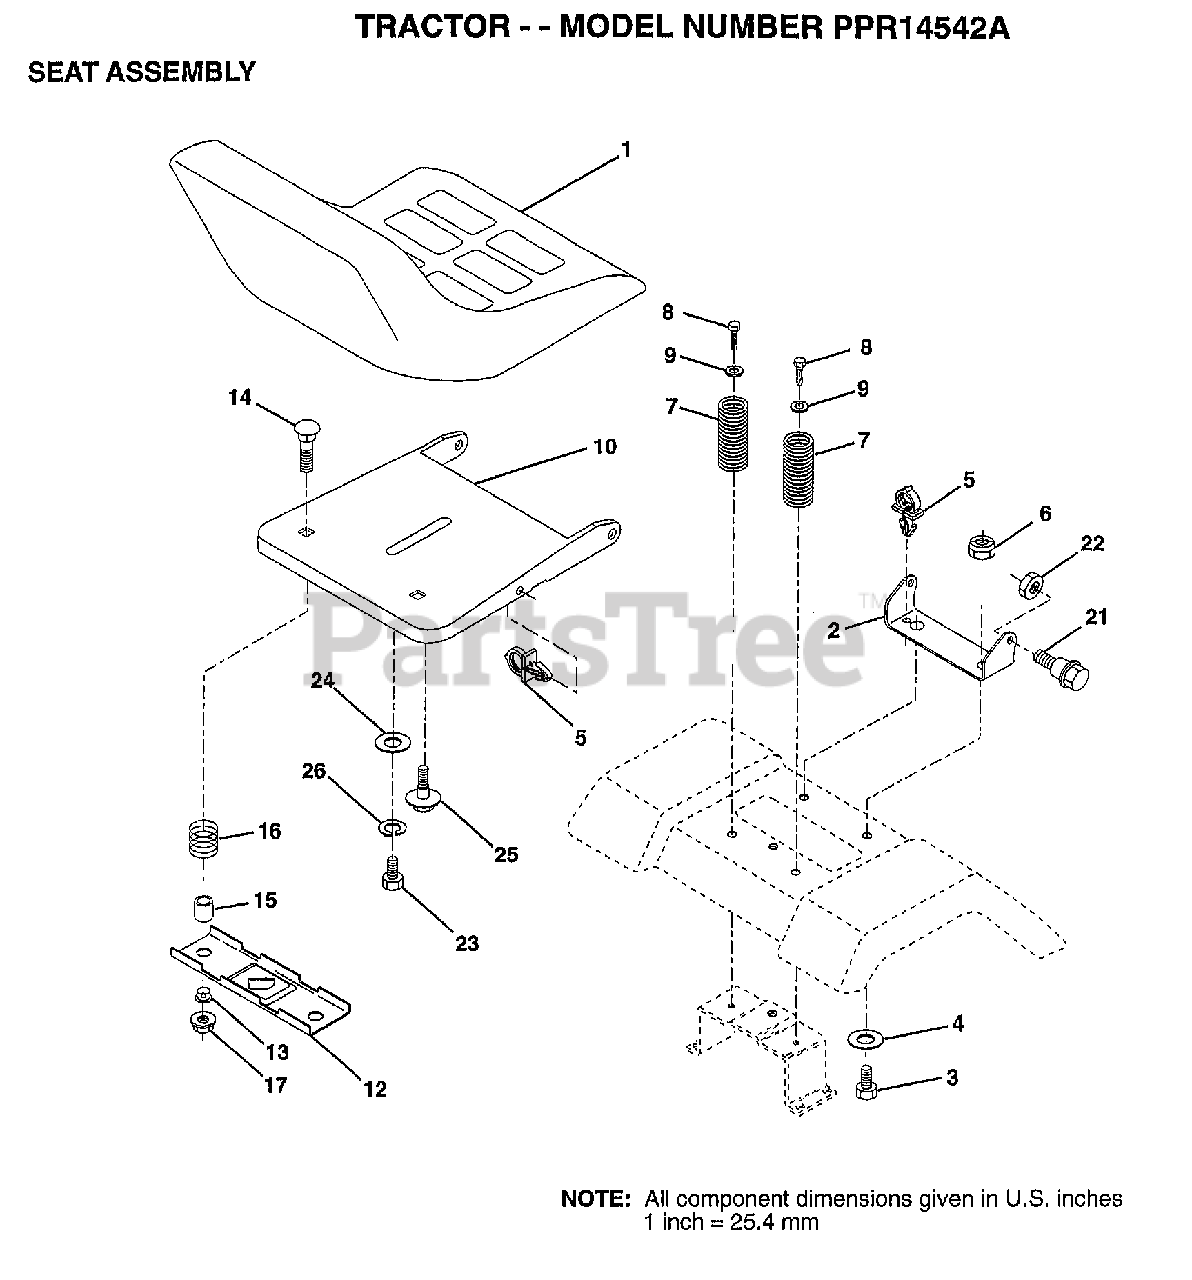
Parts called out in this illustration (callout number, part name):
1	SEAT
2	BRACKET PVT SEAT
3	BOLT
4	WASHER PM
5	CLIP.PUSH-IN.HING
6	NUT
7	SPRING COMPRESSIO
8	SCREW GTV
9	WASHER
10	PAN-SEAT
12	BRKT SWITCH
13	BUSHING
14	BOLT-RD HD SQ NK
15	SPLIT SPACER
16	SPRING
21	"BOLT,SHOULDER"
22	NUT
23	BOLT
24	WASHER
25	"BOLT,SHOULDER"
26	LOCKWASHER
